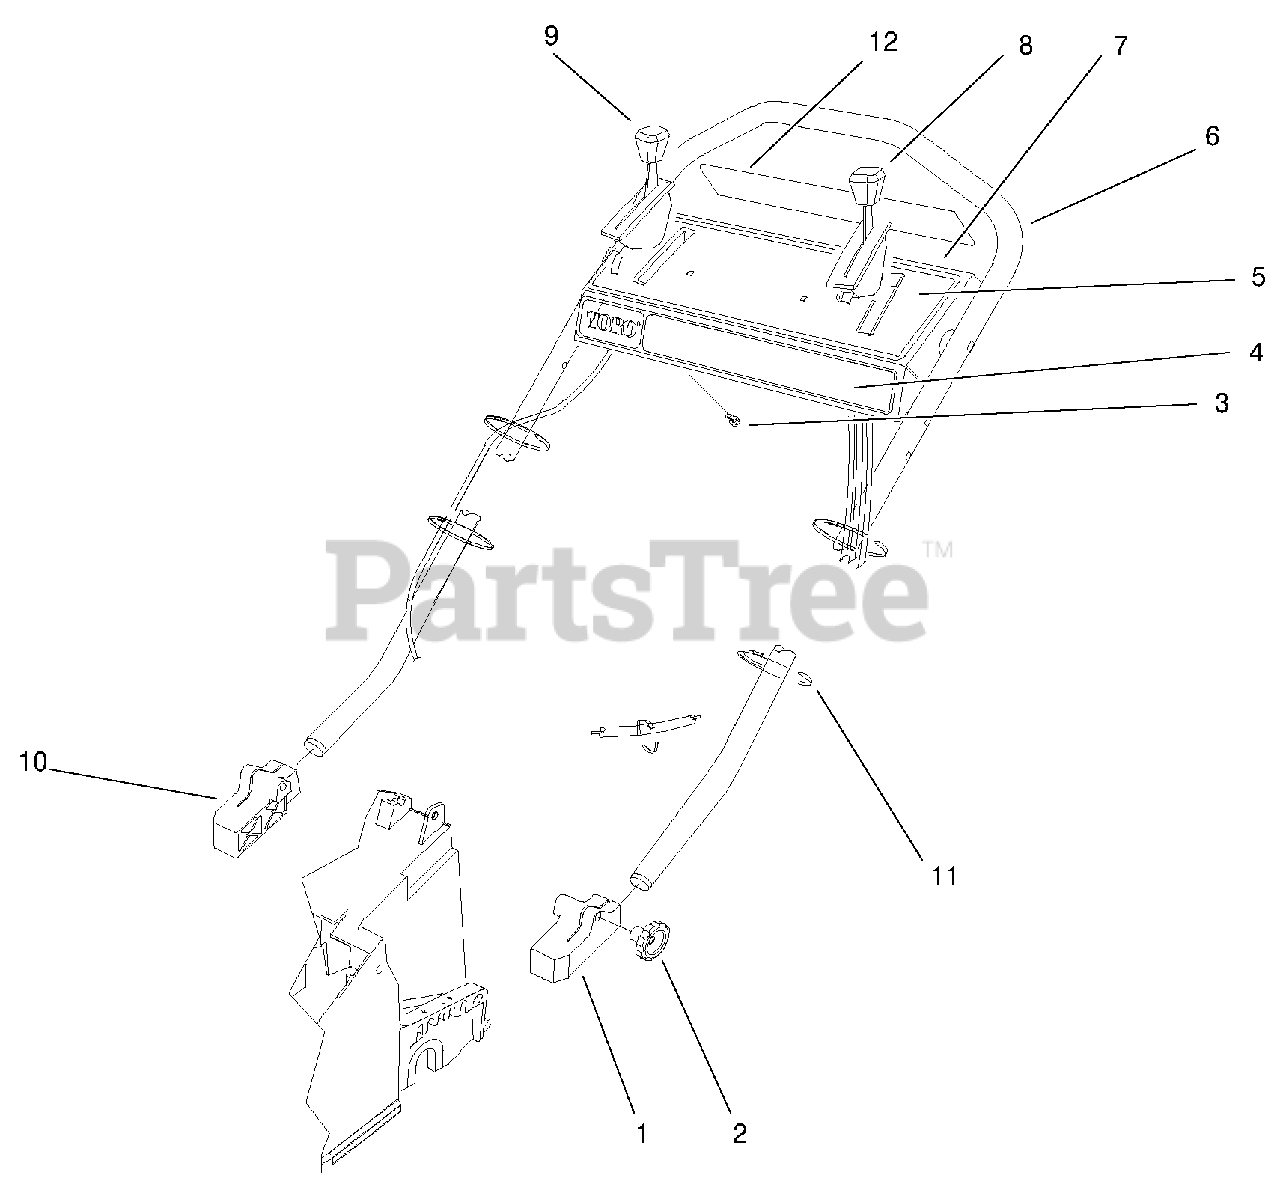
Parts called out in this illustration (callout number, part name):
1	LH Handle Mount
4	Decal-Panel
5	Decal-Instruction
8	Cable-Throttle
9	Control-Ground Speed
10	RH Handle Mount
11	Tie-Cable
12	Decal-Panel, Rear
